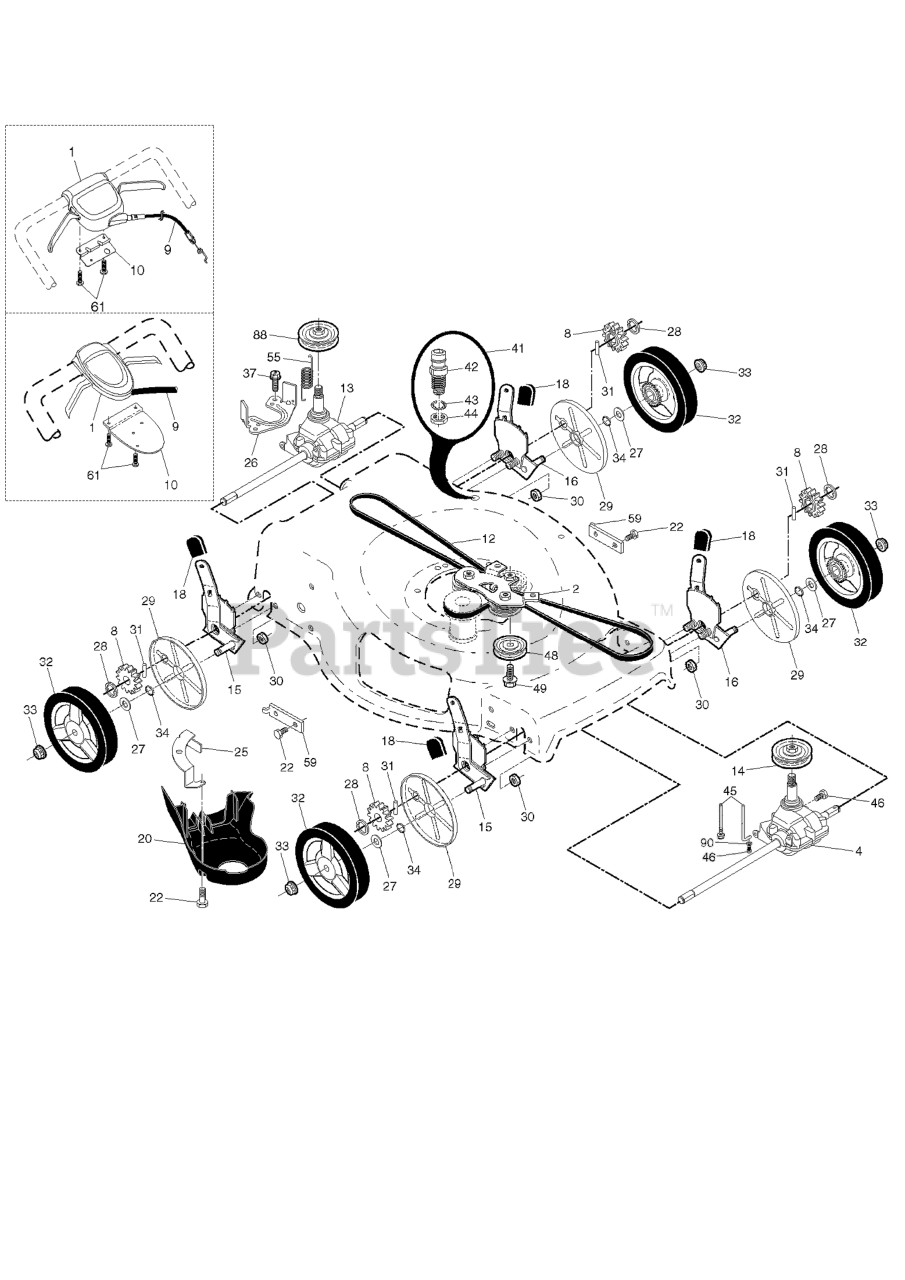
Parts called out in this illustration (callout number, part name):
1	CONTROL.DR.AW2.22+.BLK.GEN
1	CONTROL.AWD.DT.BS
2	BRACKET.ASM.AWD.BZP.BLACK
4	TRANSMISSION.22+.AWD.FRT
8	PINIION.14.TOOTH.RGD
9	CABLE.DRIVE.RWD.WALK.
10	BRACKET DUAL TRIGGER CONTROL
10	BRACKET.DRIVE.CONTR.GEN2.BLACK
12	BELT V3L 64.10 CLUTCHING COVER
13	TRANMISSION.ASM.22+AWD.REAR.14
13	TRANSMISSION.22+AWD.WALK.MOWER
14	PULLEY.DRIVE.SM.AWD/RWD
15	ADJUSTER.ASM.22+FGD.RF /AWD RT
16	ADJUSTER.ASM.22+FGD.LF /AWD LT
18	SELECTOR KNOB
20	COVER.REAR.DRIVE.22+2013
22	BOLT.5/16HEX.WHS.HD
25	BRACKET.DRIVE.COVER.RGD.BZP
26	BRACKET.TRAN.BELTKEEPER.22+RGD
27	WASHER FLUT
28	E-RING 7/16 RE
29	COVER.DUST.WHEEL.INNER.WALK
30	NUT.FLANGE.1-4-20-SERR
31	PAWL, DRIVE
32	WHEEL.8".AWD.3SP.EXT.DR.GREY
33	NUT.HEX.FLANGE.3/8-16.LO(3 2)
34	O-RING..070X.487.NEOPRENE
41	KIT.WASH-OUT.PORT.ZINC.WALK
42	WASHOUT.PORT.ZINC.RGD.22+
43	WASHER.LOCK.INTERNAL.TOOTH
44	LOCKNUT.HEX.WITH.O-RING
45	SCREW.HI-LO.5/16-14 X 4.10
45	BRACKET.AWD.FRONT.BELT.KEEPER
46	SCREW.HI-LO. 5/16 X 1.00
48	PULLEY.ASM.22+ AWD
55	SPRING.RETURN.AUTO.
59	BRACKET.SUPPORT.22+RWGD.BZP
61	SCREW, PHILLIPS HEAD 10 X 5/8
88	RP PULLEY.PM.22+AWD
88	PULLEY
90	WASHER 5/16 FLAT
